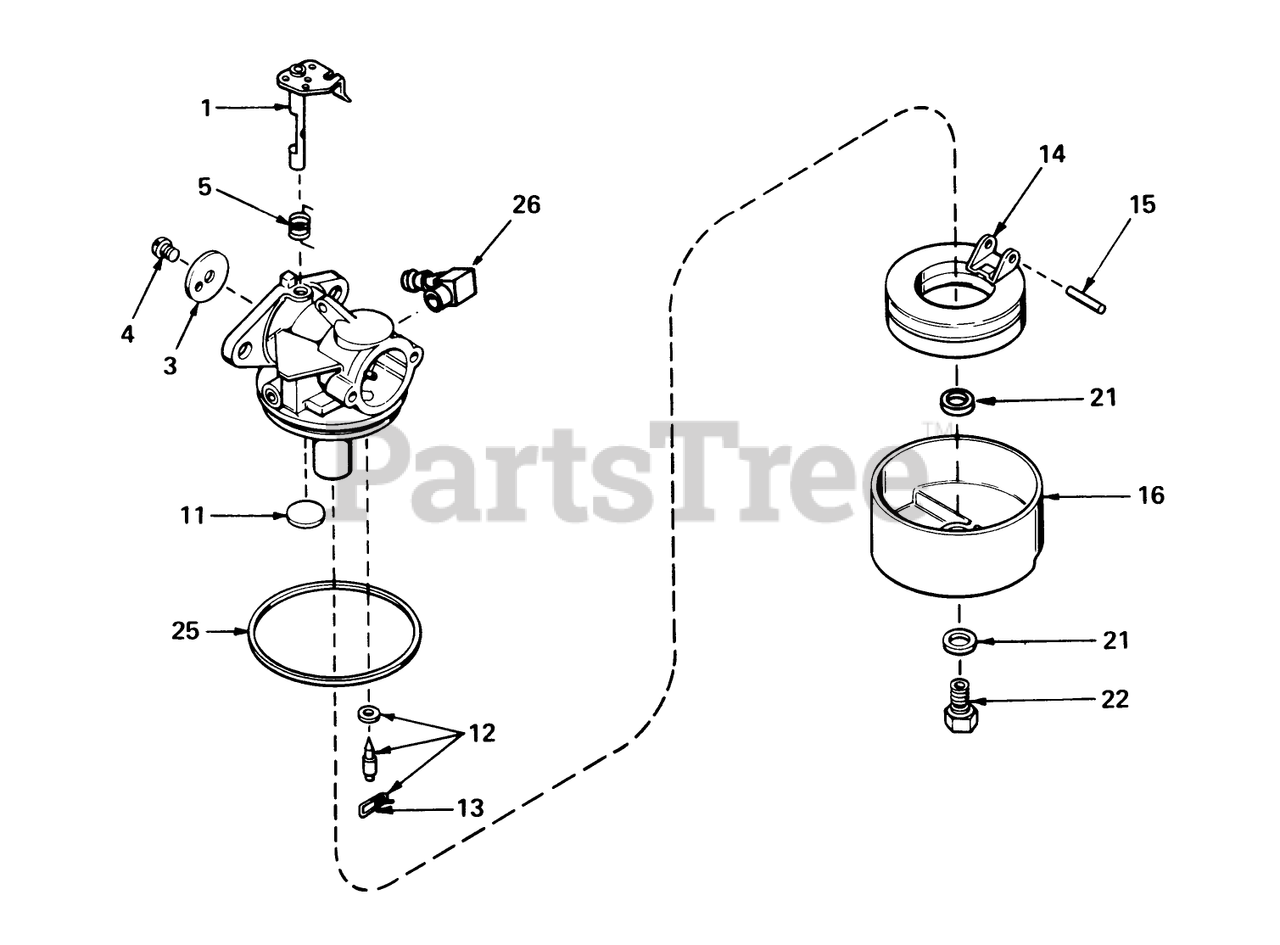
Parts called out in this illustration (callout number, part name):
1	Throttle Shaft and Lever ASM
3	Throttle-Shutter
4	Screw-Shutter
5	Spring, Return
11	Plug-Welch, Atmospheric Vent
12	Inlet Needle, Seat Clip Assy. (Incl. No. 13)
13	Clip-Spring
14	Float, Carburetor
15	Shaft-Float
16	Bowl Float
21	Gasket-Bowl
22	Nut-Float Bowl
25	O Ring-Bowl, Float
26	Fitting-Fuel
